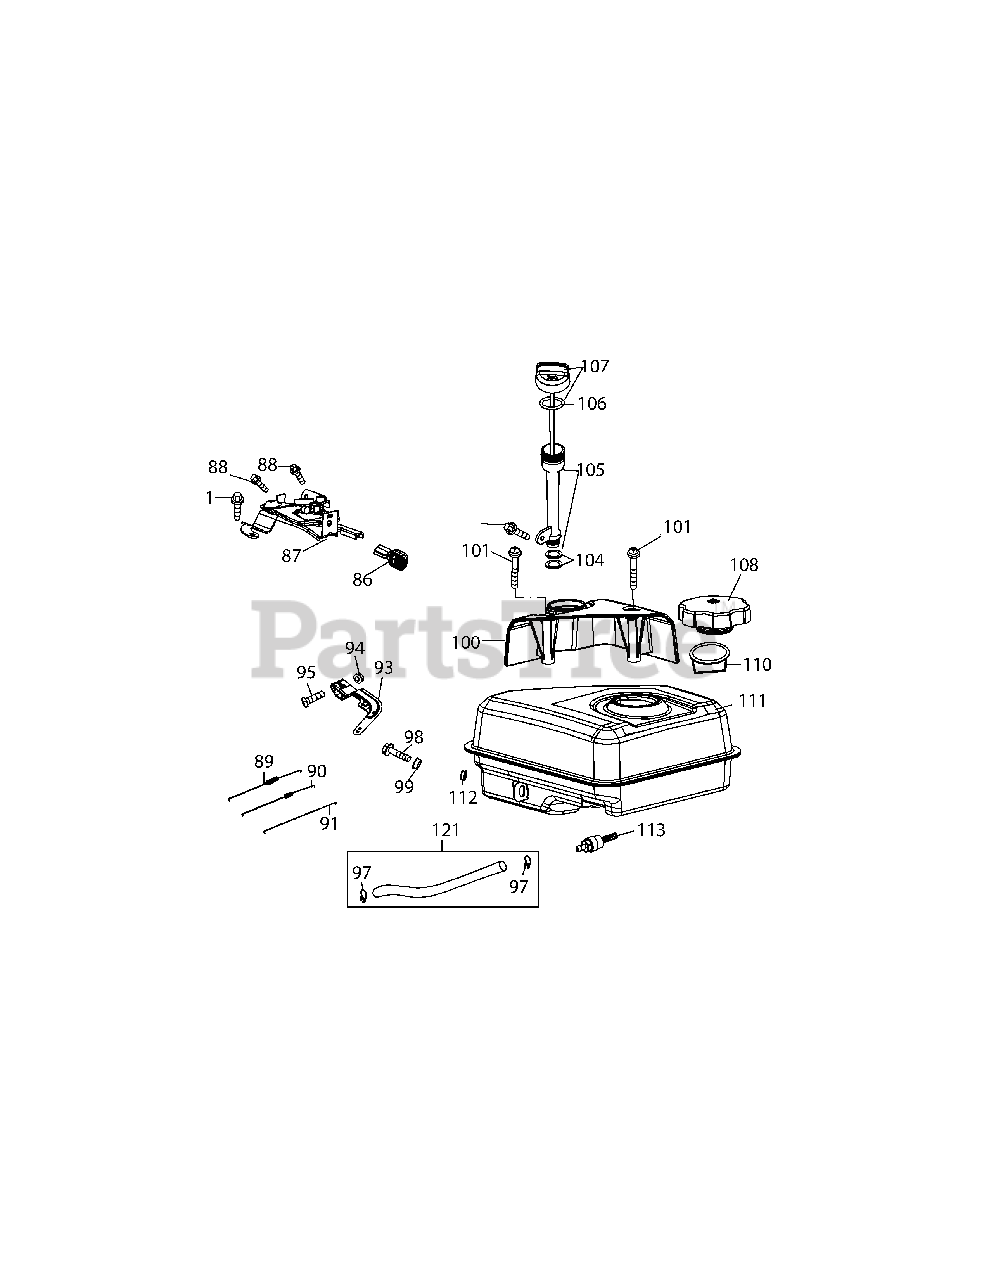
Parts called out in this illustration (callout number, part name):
1	Bolt M6×16
86	Throttle Control Knob
87	Primer Bracket
88	Bolt M6×12
89	Governor Spring
90	Throttle Linkage Spring
91	Throttle Linkage
93	Governor Arm
94	Nut M6
95	Governor Arm Bolt
97	Fuel Hose Clamp
98	Bolt M6×20
99	Grommet 8.5 x 9
100	Dipstick Cover
102	Bolt M6×12
104	Oil Fill Tube O-Ring
105	Oil Fill Tube
106	Oil Fill Tube O-Ring
107	Dipstick Guage
108	Fuel Cap Assembly
110	Fuel Filter
112	Rubber Shock Pad
113	Fuel Tank Nipple
121	Fuel Line Kit
